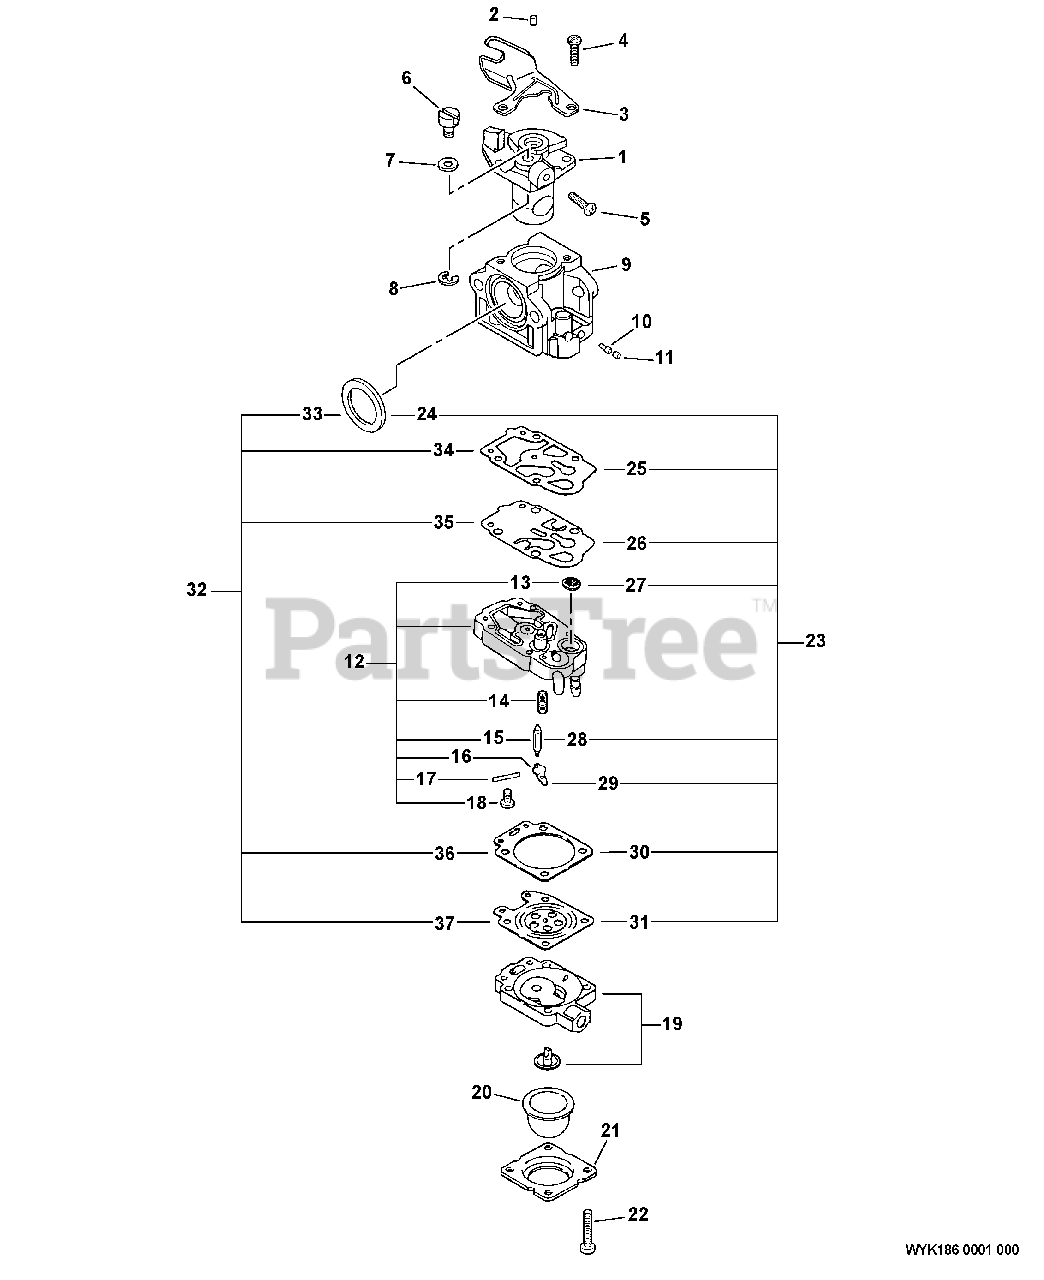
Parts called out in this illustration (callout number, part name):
1	THROTTLE VALVE ASSY
3	BRACKET, THROTTLE CABLE
9	BODY, CARBURETOR
10	NEEDLE, HIGH SPEED
12	PUMP BODY ASSY
13	STRAINER
14	SPRING, METERING LEVER
15	VALVE, INLET NEEDLE
16	LEVER, METERING
17	PIN, METERING LEVER
19	BODY ASSY, PURGE
20	BULB, PURGE
21	RETAINER, PURGE BULB
23	REPAIR KIT, CARBURETOR
24	SEAL
25	GASKET, PUMP
26	DIAPHRAGM, PUMP
27	STRAINER
28	VALVE, INLET NEEDLE
29	LEVER, METERING
30	GASKET, DIAPHRAGM
31	DIAPHRAGM, METERING
32	DIAPHRAGM/GASKET KIT
33	SEAL
34	GASKET, PUMP
35	DIAPHRAGM, PUMP
36	GASKET, DIAPHRAGM
37	DIAPHRAGM, METERING
